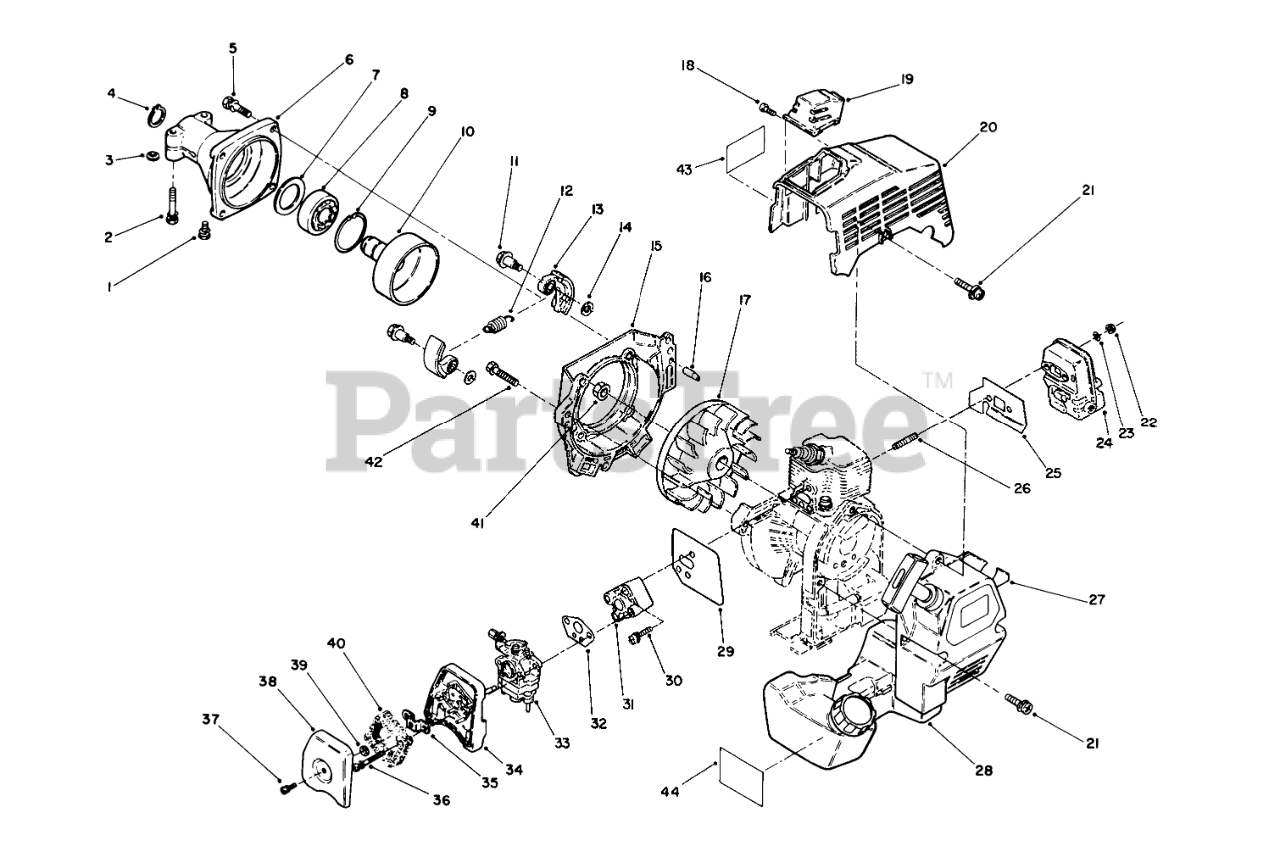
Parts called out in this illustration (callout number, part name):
1	Screw/Washer
2	BOLT-WASHER/ENG
3	WASHER
4	SNAP RING
5	Bolt/Washer
6	CLUTCH CASE
7	Washer
8	BALL BEARING
9	SNAP RING
10	CLUTCH DRUM
11	CLUTCH BOLT
12	Spring
13	SHOE, CLUTCH
14	WASHER
15	Case-Fan
17	Fan
18	SCREW & WASHER
19	SPARK PLUG GUARD
20	TOP COVER
21	SCREW & WASHER
22	MUFFLER FLANGE NUT
23	GASKET
24	MUFFLER ASSEMBLY
25	MUFFLER GASKET
26	MUFFLER STUD
27	Starter-Recoil
28	Tank Assembly-Fuel
29	INSULATOR GASKET
30	SCREW & WASHER
31	INSULATOR
32	CARBURETOR GASKET
33	Carburator Assembly
34	CLEANER CASE
35	BRACKET
36	SCREW W/ WASHER
37	SCREW & WASHERE
38	CLEANER COVER
40	CLEANER ELEMENT
42	BOLT AND WASHER
43	DECAL-SURFACE, HOT
44	DECAL - FUEL TANK
